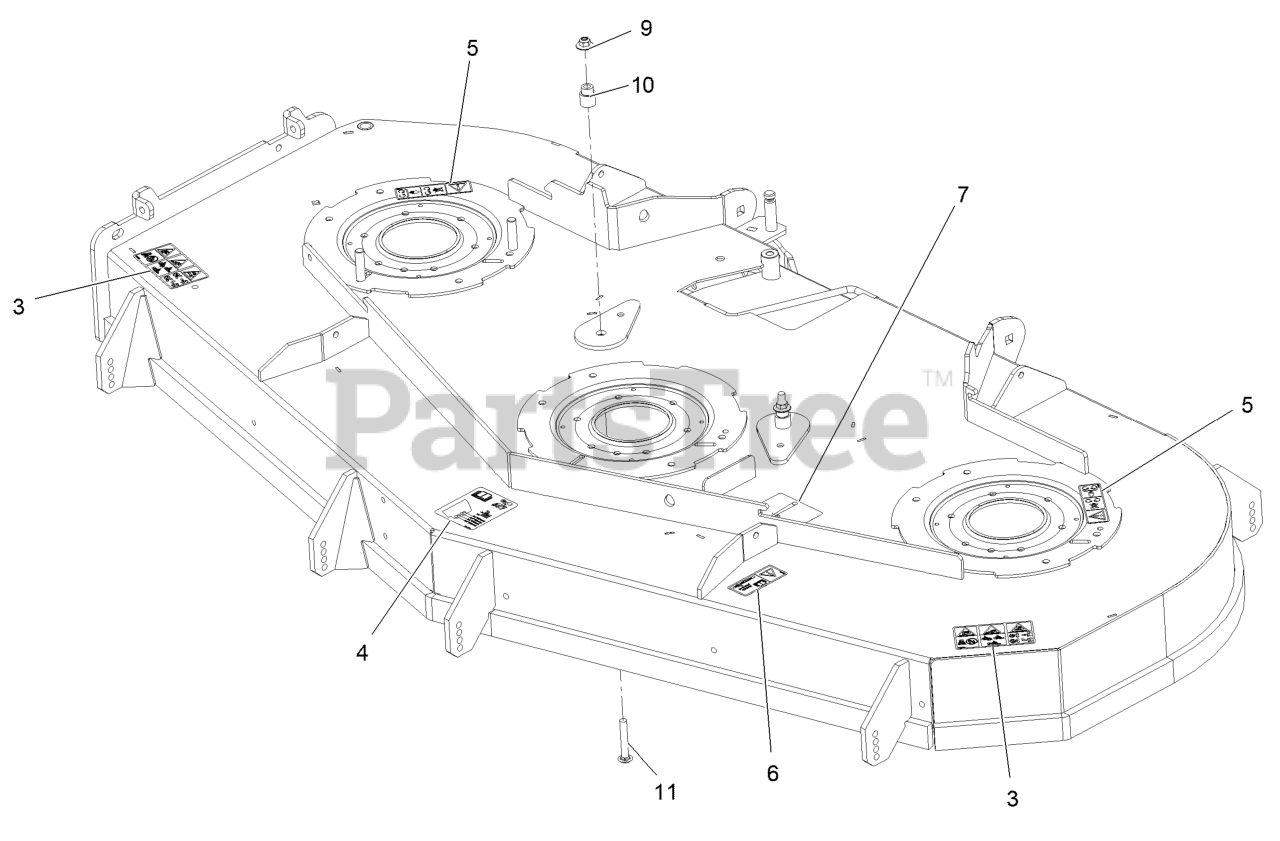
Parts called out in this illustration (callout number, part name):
3	DECAL-DANGER THROWN OBJECTS
4	DECAL-ROLLER, ANTI-SCALP
5	DECAL-COVER, MISSING
6	DECAL-BOLT TORQUE
7	DECAL-BELT ROUTING
9	Nut-Nyloc 3/8-16 Flg
10	BUSHING-IDLER
11	SCREW-CARR
